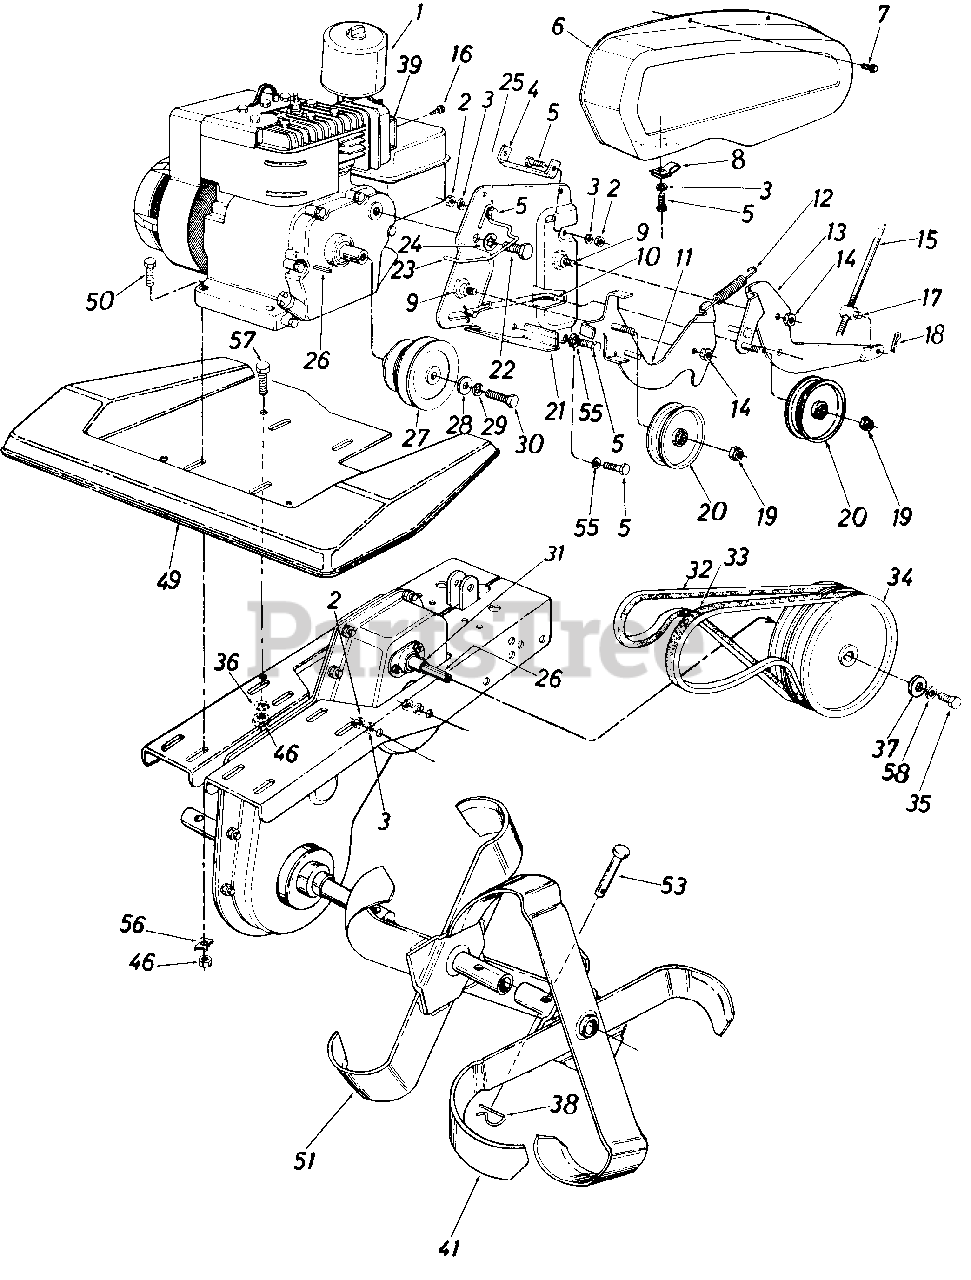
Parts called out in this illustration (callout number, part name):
1	Engine
2	Hex Nut 1/4-20 Thd.
3	L-Wash. 1/4" I.D.*
4	Support Bracket
5	Hex Bolt 1/4-20 x .75" Lg.
8	"U"-Type Speed Nut
9	Shoulder Bolt .625 Dia. x .170 Lg.
10	Gontrol Rod
11	Reverse Idler Brkt. Ass'y.
12	Spring-Idler Brkt.
13	Forward Idler Brkt. Ass'y.
14	Hex Cent. L-Nut 3/8-16 Thd.
15	Clutch Control Rod
16	Hex Self-Tap Scr. #8-32 x .38" Lg .
17	Ferrule
18	Inter. Cotter Pin
19	Hex Jam Nut 3/8-24 Thd.
20	Fl-Idler w/Flanges 3.12 O.D. x .75
21	Clutch Mounting Plate
22	Hex Bolt 1/2-20 x .75 Spec.
23	Belt Guard Rod
24	Internal L-Wash. 1/2" I.D.
25	Fl-Wash. 1/4" I.D.
26	Sq. Key 3/16" x 1.50n Lg.
27	Engine Pulley
28	Fl-Wash. 3/8" I.D. x 1.00n
29	L-Wash 3/8" I.D.
30	Hex Bolt 3/8-24 x 1.25" Lg.*
31	Spacer .635 I.D. x .88 O.D. x 1.035 Lg.
32	"V"-Belt 1/2" x 41" Lg. Reverse
33	"V"-Belt 1/2" x 37" Lg. Forward
34	Chain Case Pulley 6.0" Dia.
35	Hex Bolt 5/16-18 x 1.0" Lg.
36	Shake-Proof Wash.
37	Fl-Wash. 5/16" I.D. x 1.120
38	Internal Cotter Pin 1/2" Dia.
39	Deflector
41	See Tine Chart Below
51	See Tine Chart Below
55	Bell-Wash.
56	Shake-Proof Wash.
57	Hex Bolt 5/16-18 x .75" Lg.
58	L-Wash. 5/16n I.D.
